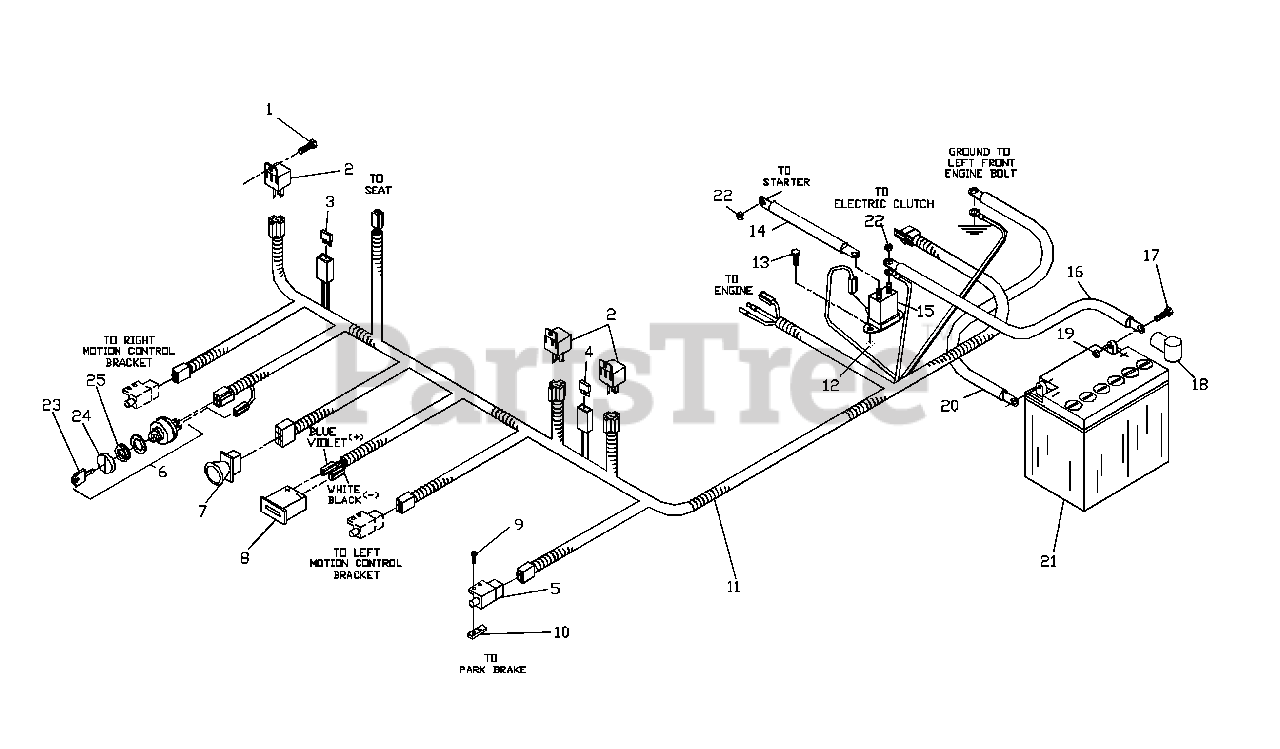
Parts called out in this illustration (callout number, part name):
1	#10 X 1/2 SELF TAPPING
3	7.5 AMP 32 VOLT ATO FUSE
4	20 AMP 32 VOLT ATO FUSE
5	INTERLOCK SWITCH
6	IGNITION SWITCH
7	BLADE SWITCH
8	HOUR METER
9	#10-24 X 5/8
10	TAPPED PLATE
11	WIRING HARNESS
12	NUT 1/4C CENTERLOCK
13	HCS 1/4C X 5/8
14	CABLE POSITIVE
16	CABLE POSITIVE, LONG
17	HCS 5/16C X 3/4
19	NUT 5/16C CENTERLOCK
20	CABLE NEG.
21	BATTERY
22	NUT 1/4C NYLOC
23	KEY, PADDED
